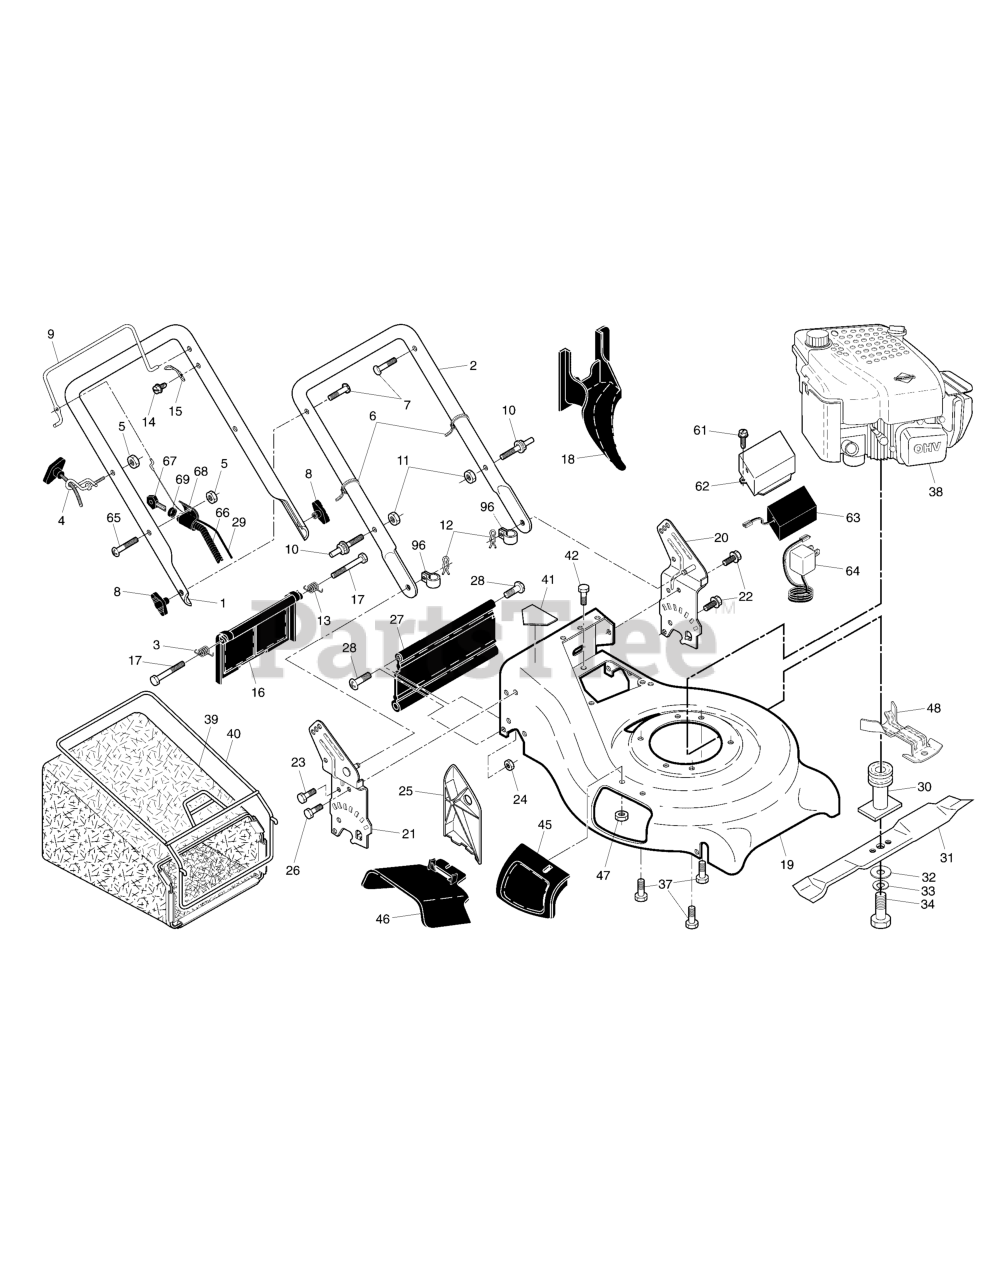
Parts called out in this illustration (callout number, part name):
1	Handle, Upper
2	** Handle, Lower
3	** Spring, Rear Door, RH
4	Rope Guide
5	Nut, Hex, with Lockwasher Insert, 1/4-20
6	Wire, Tie
7	Bolt, Handle 5/16-18 x 2-5/8
8	Knob, Handle
9	Control Bar
10	** Pin, Handle Adjustment
11	Nut, Hex
12	Cotter, Hairpin
13	** Spring, Rear Door, LH
15	Bracket, Upstop
16	** Rear Door Assembly
17	Bolt, Rear Door
18	** Plug, Mulcher
19	** Kit, Housing
20	** Handle Bracket Asembly, LH
21	** Handle Bracket Assembly, RH
22	Screw, Hex Washer Head
23	** Bolt, Hex Head 5/16-18 x 5/8
24	Nut, Hex, with Lockwasher Insert 5/16-18
25	** Baffle, Side
26	Screw #12 x 5/8
27	** Skirt, Rear
28	Screw, Hinge 1/4-20 x 1.25
29	** Cable, Operator Presence
30	Blade Adapter / Pulley
31	Blade, 21"
32	Washer
33	Washer, Lock
34	Bolt, Hex Head
37	Bolt, Engine
38	* Engine, Briggs & Stratton
39	** Grassbag
40	** Frame, Grassbag
41	Danger Decal
42	Screw, Hex Washer Head
45	** Mulcher Door Assembly
46	** Discharge Guard
47	Nut, Hex
48	Belt Keeper
61	Screw, Hi-Lo Thread
62	** Battery Box
63	** Battery
64	** Battery Charger, C.E.
65	** Screw
66	** Wiring Harness
67	** Key
68	** Key Start Switch
69	** Nut, Cap
96	Clip, Cable
